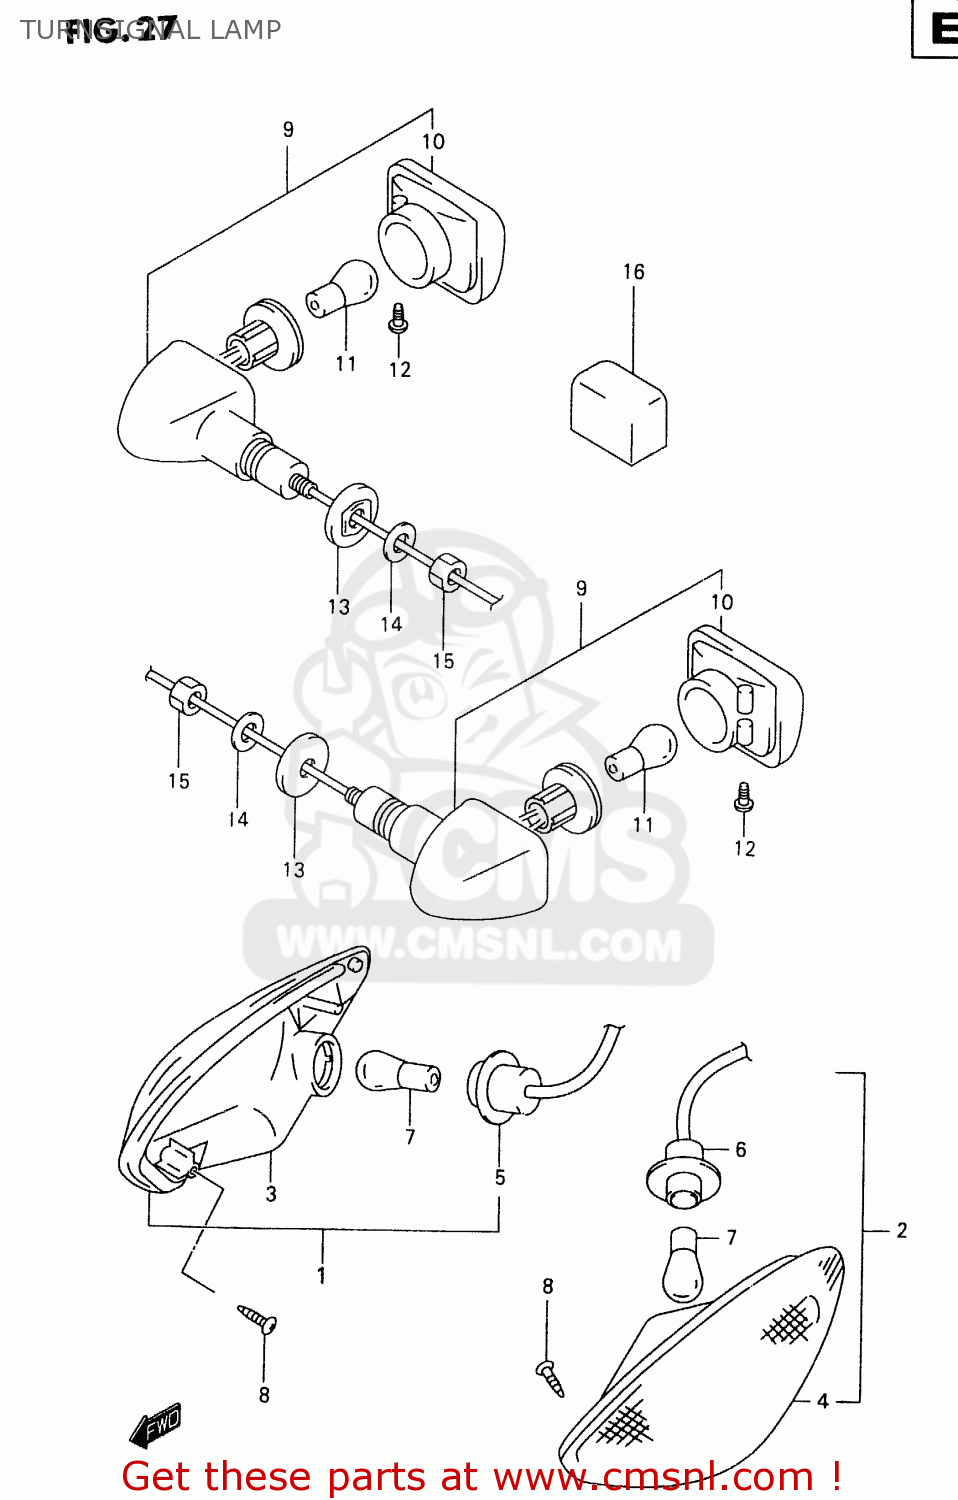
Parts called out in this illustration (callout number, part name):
1	LAMP ASSY,FR TURN SIGNAL,R
2	LAMP ASSY,FR TURN SIGNAL,L
3	LAMP UNIT,R
4	LAMP UNIT,L
5	SOCKET & CORD
6	SOCKET & CORD
7	BULB(12V21W)
8	SCREW
9	LAMP ASSY,RR TURNSIGNAL,R
10	LAMP UNIT
11	BULB(12V21W)
12	SCREW
13	SPACER,RR TURNSIGNAL
14	WASHER(10.5X30X2.3)
15	NUT
16	RELAY ASSY,TURNSIGNAL LAMP
